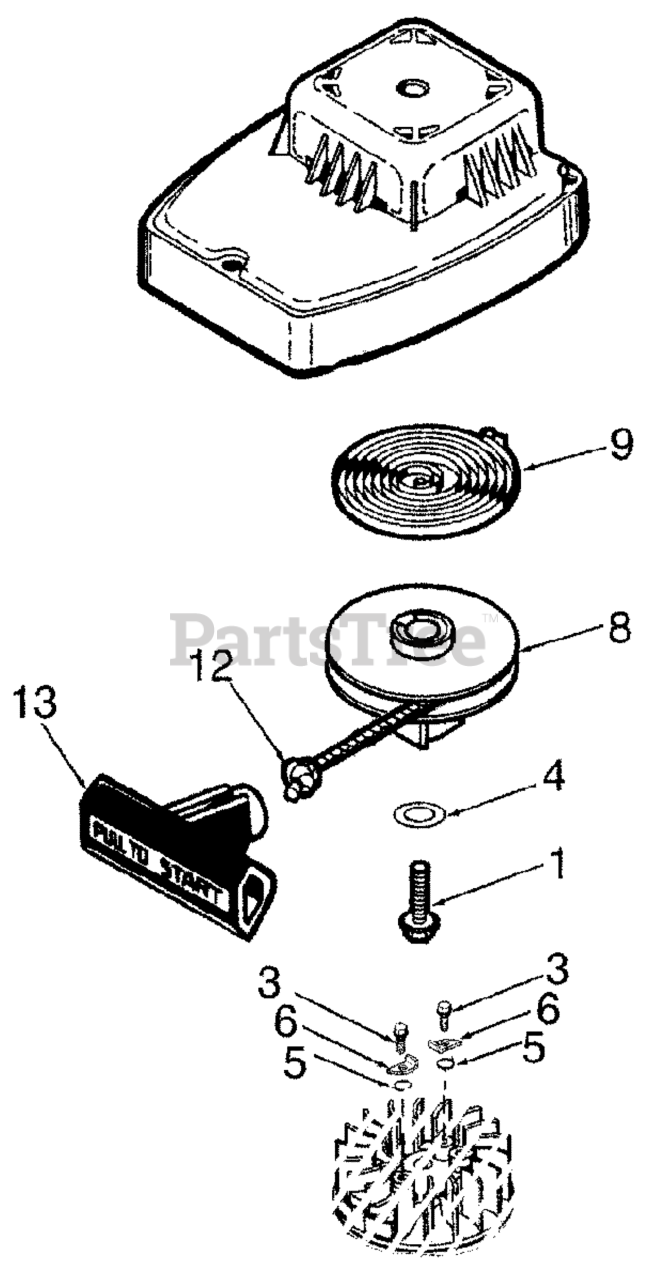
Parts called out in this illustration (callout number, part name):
1	Retainer Screw, 10-24 x 1-3/8"
3	Pawl Screw, 12-24 x 11/64"
4	Washer
8	BASE, Air Cleaner
13	Starter Handle
